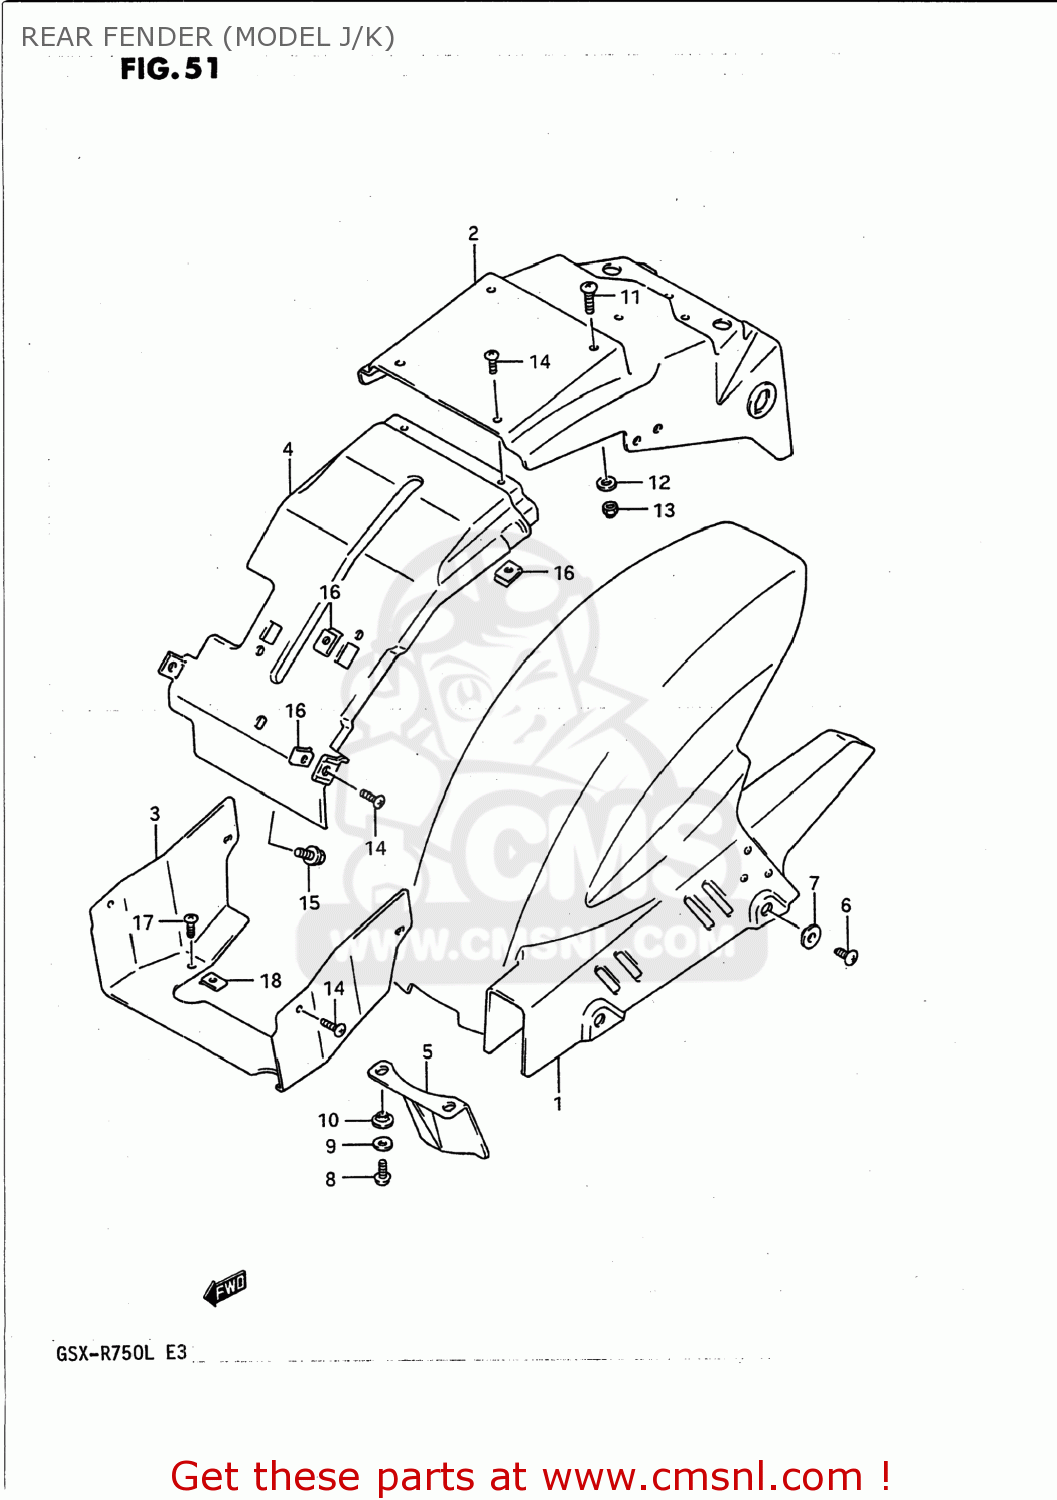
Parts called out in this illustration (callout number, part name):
1	FENDER,RR LWR
2	FENDER,REAR
3	FENDER,REAR
4	FENDER,RR UPR FR NO.2
5	GUARD,RR UNIT MUD
6	SCREW
7	WASHER
8	SCREW
9	WASHER(6.5X16X1.2)
10	WASHER,LOCK
11	SCREW
12	WASHER
13	NUT 6MM
14	SCREW, FRONT & REAR
15	BOLT
16	NUT,HEADLAMP HOUSING,UPPER
17	SCREW, FRONT & REAR
18	NUT,HEADLAMP HOUSING,UPPER
